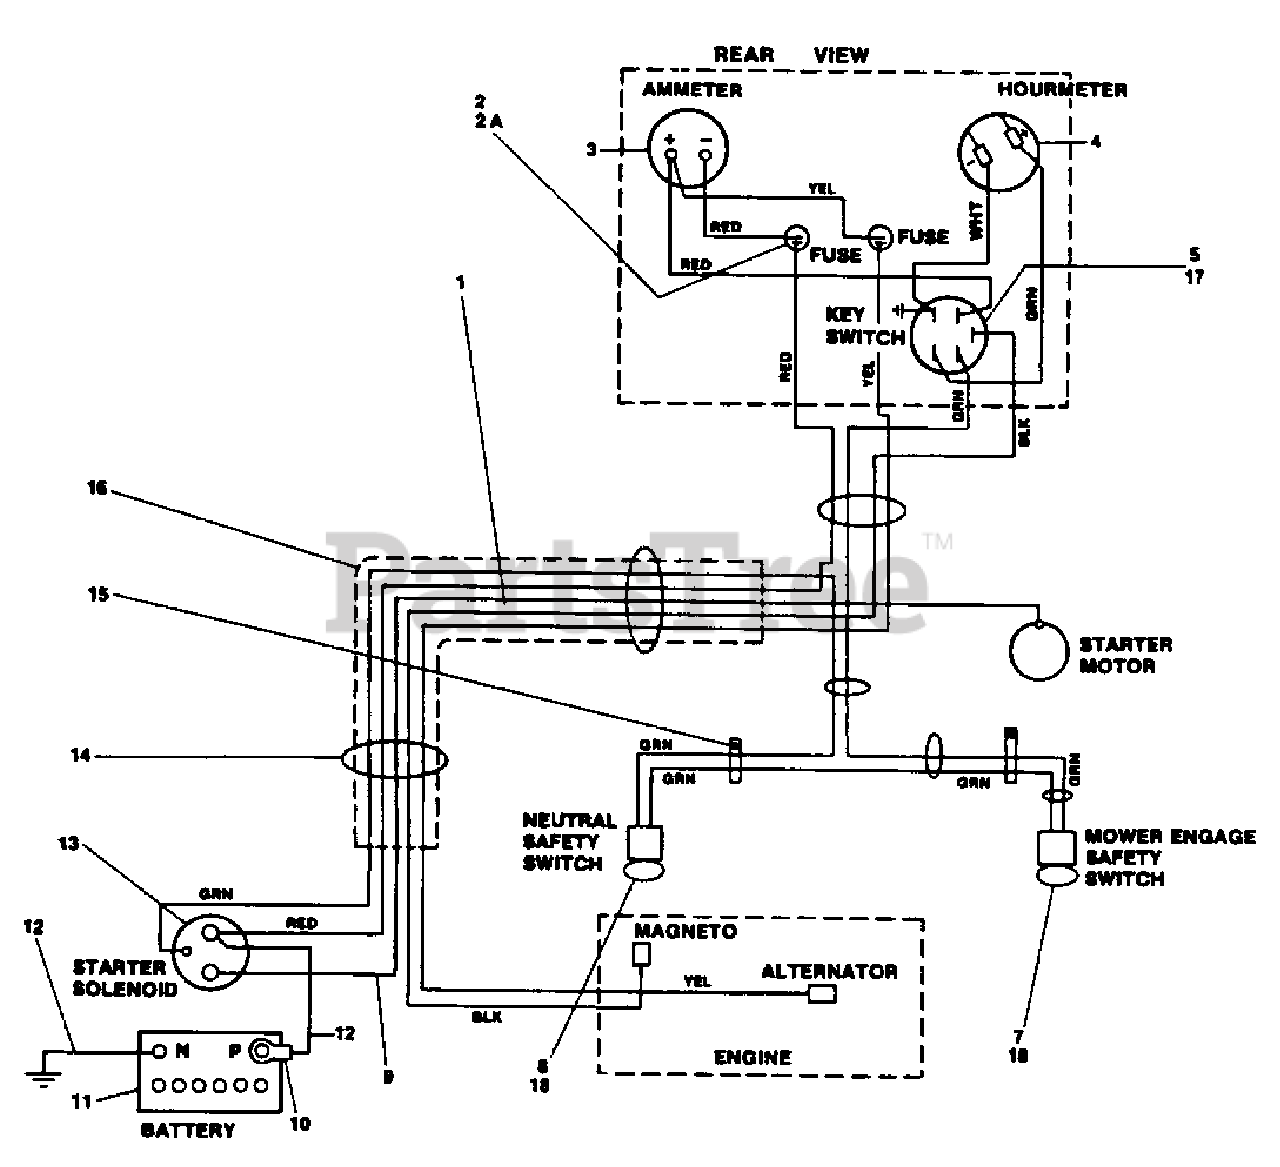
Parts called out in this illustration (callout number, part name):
1	WIRING HARNESS, B&S 18 HP E.S.
2	FUSE HOLDER
2A	FUSE, 20A
3	AMMETER
4	HOUR METER
5	KEY SWITCH
7	MOWER ENGAGE SAFETY SWITCH
8	NUETRAL SAFETY SWITCH
9	BATTERY CABLE
10	RUBBER BOOT
11	BATTERY
12	BATTERY CABLE
13	STARTER SOLENOID
14	CABLE TIE
15	CABLE CLAMP
16	PLASTIC CONDUIT
17	CONNECTOR, STARTER SWITCH
